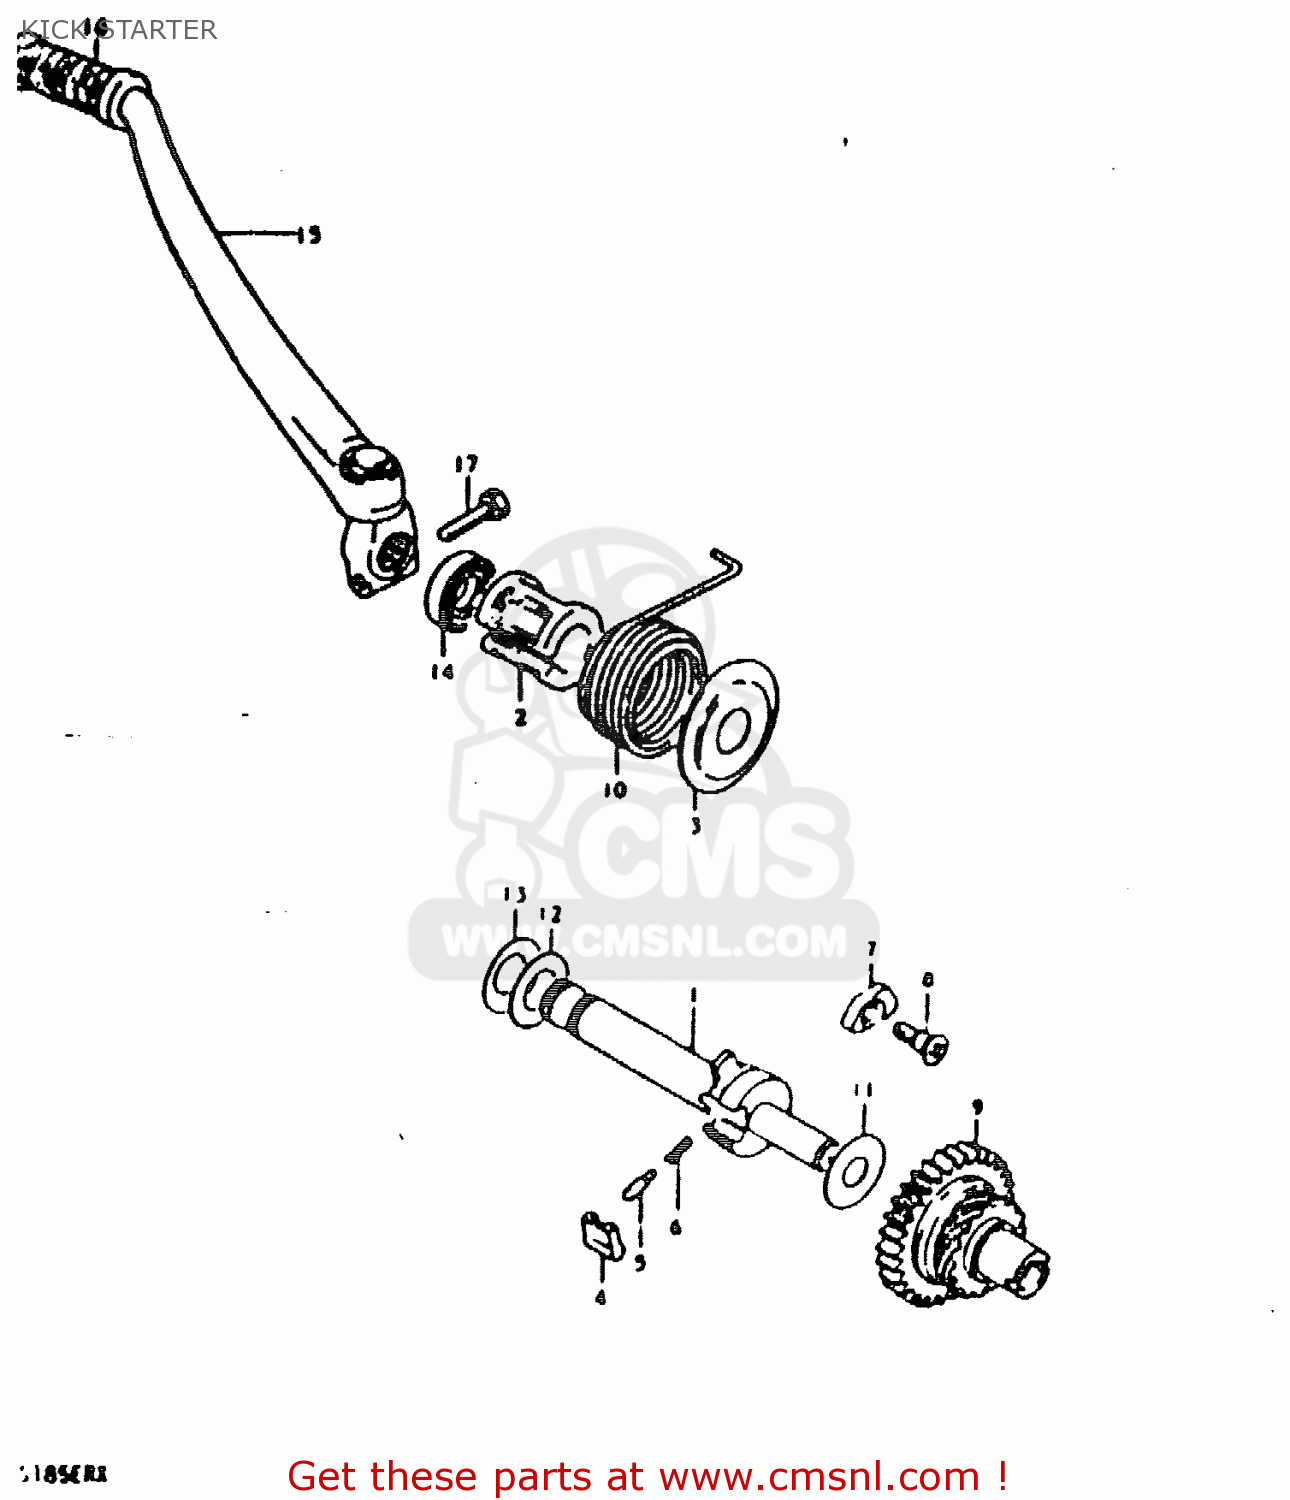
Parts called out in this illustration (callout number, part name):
1	SHAFT,KICK STARTER
2	GUIDE,KICK STARTER SFT SPRING
3	HOLDER,KICK STARTER SHAFT SPR
4	PAWL,KICK STARTER
5	PIN(5X15.5)
6	SPRING
7	LIFTER,KICK STARTER PAWL
8	SCREW(6X19)
9	GEAR,KICK STARTER DRIIVE
10	SPRING
11	WASHER(12X30X3)
12	WASHER(16X30X0.5)
13	WASHER
14	SEAL,OIL(16X30X8)
15	LEVER ASSEMBLY,KICK STARTER
16	RUBBER,KICK STARTER PEDAL
17	BOLT
